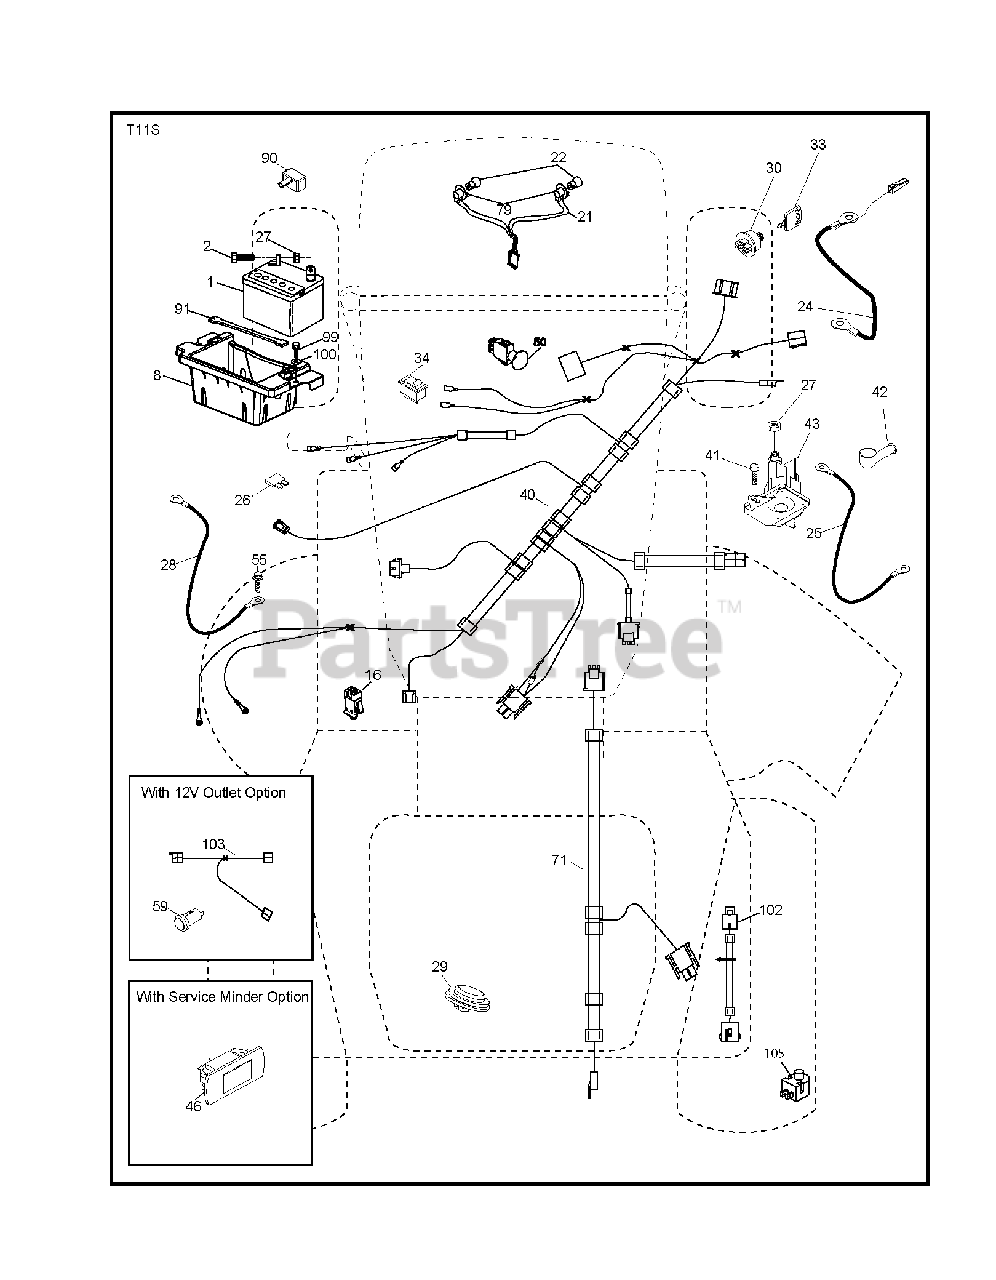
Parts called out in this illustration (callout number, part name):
1	REPL BY 532 12 38-99
2	BOLT.HEX.1/4.X.3/4.DICHROMATE
8	BOX.BATTERY.MOUNT.FRONT.LT
16	HARNESS ASSY LIGHT
21	HARNESS ASSY LIGHT
22	LIGHTBULB
24	CABLE.BATT.POS.WIRE.TG.DA SOL
25	CABLE.STARTER.6GA.BL/RED.14.
26	FUSE 20AMP
27	NUT
28	CABLE GROUND 6 GA 21" 90T BLK
29	SWITCH.SEAT.DELTA.OPC.
30	SWITCH.IGN.DELTA.W.LGH.ROS
33	KEY.CHAIN.BLISTER.PACK.GEN.USA
34	SWITCH LT
40	HARNESS.IGN.DASH.HUQ/P
41	SCREW
42	TERMINAL COVER
43	SOLENOID.W/BRASS.PLUNGER
46	GUAGE.SRVCMNDR.HRMTR.
50	PTO SWITCH
55	SCREW 5/16"
71	HARNESS-CHASSIS SUB
79	BULB HOLDER ASM.
90	COVER.TERMINAL.BATTERY
91	STRAP.BATTERY.MOUNT.FRONT
99	SCREW HEXWSHR 1/4-20X3/4
102	HARNESS PIGTAIL PCH TEX ROS
105	REVERSE SWITCH
